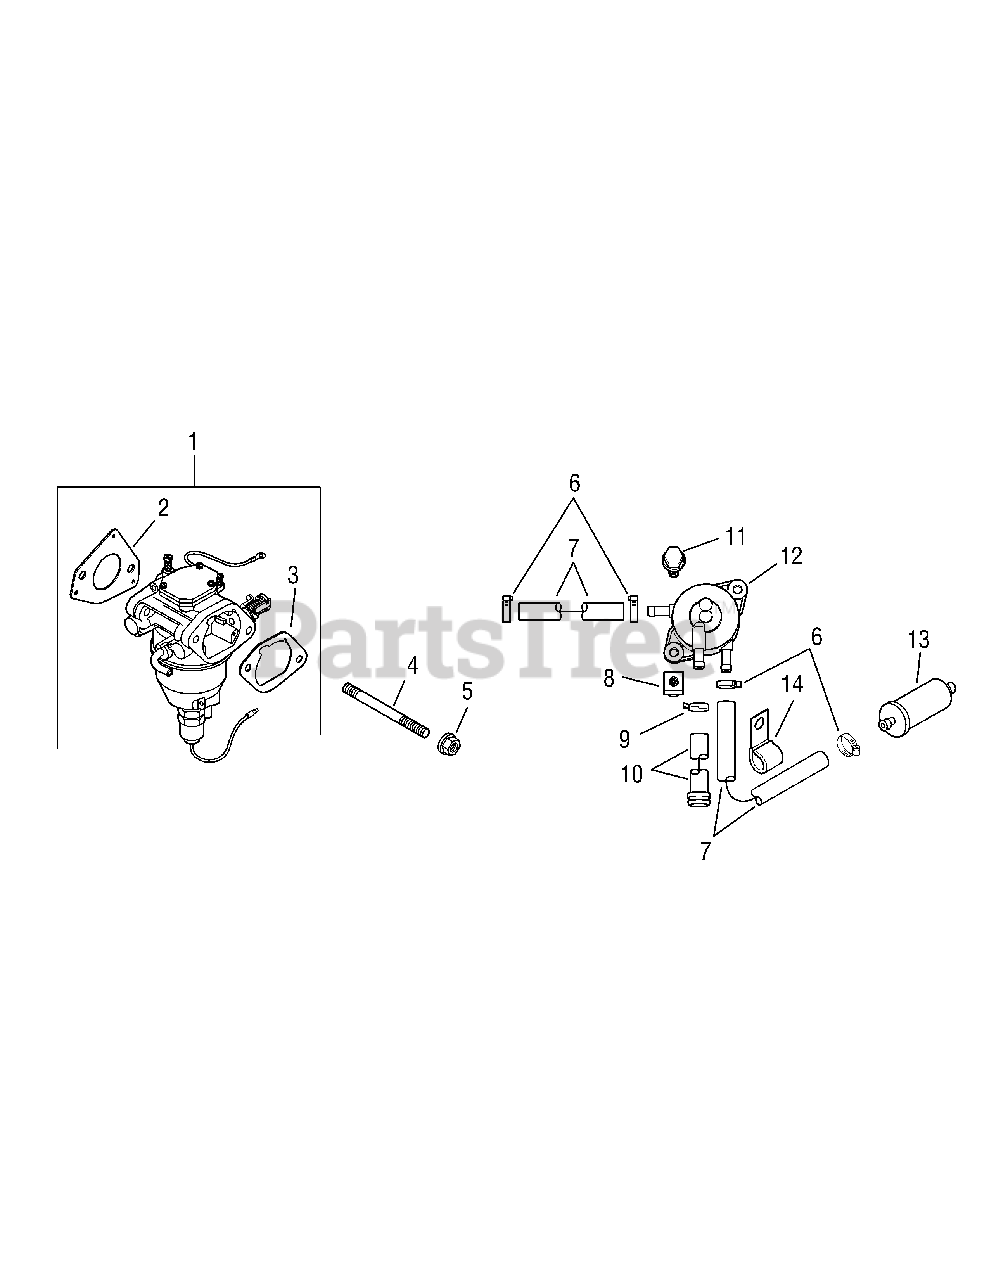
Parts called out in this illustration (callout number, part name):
1	Carburetor Kit w/ Gaskets (Inc. 2 & 3)
2	Carburetor Gasket
3	Air Cleaner Base Gasket
4	Carburetor Stud
5	Hex Flange Nut, M6 x 1.0
6	Hose Clamp
7	Fuel Line, 24
8	Plastic Nut
10	Fuel Pump Hose
11	Hex Cap Screw, M6 x 1.7 x 18
12	Pulse Fuel Pump
NS	Service Choke Repair Kit
NS	Service Gasket Repair Kit
NS	Float Kit w/ Gaskets
NS	Solenoid Valve Kit w/ Gaskets
NS	Overhaul Kit w/ Gaskets
